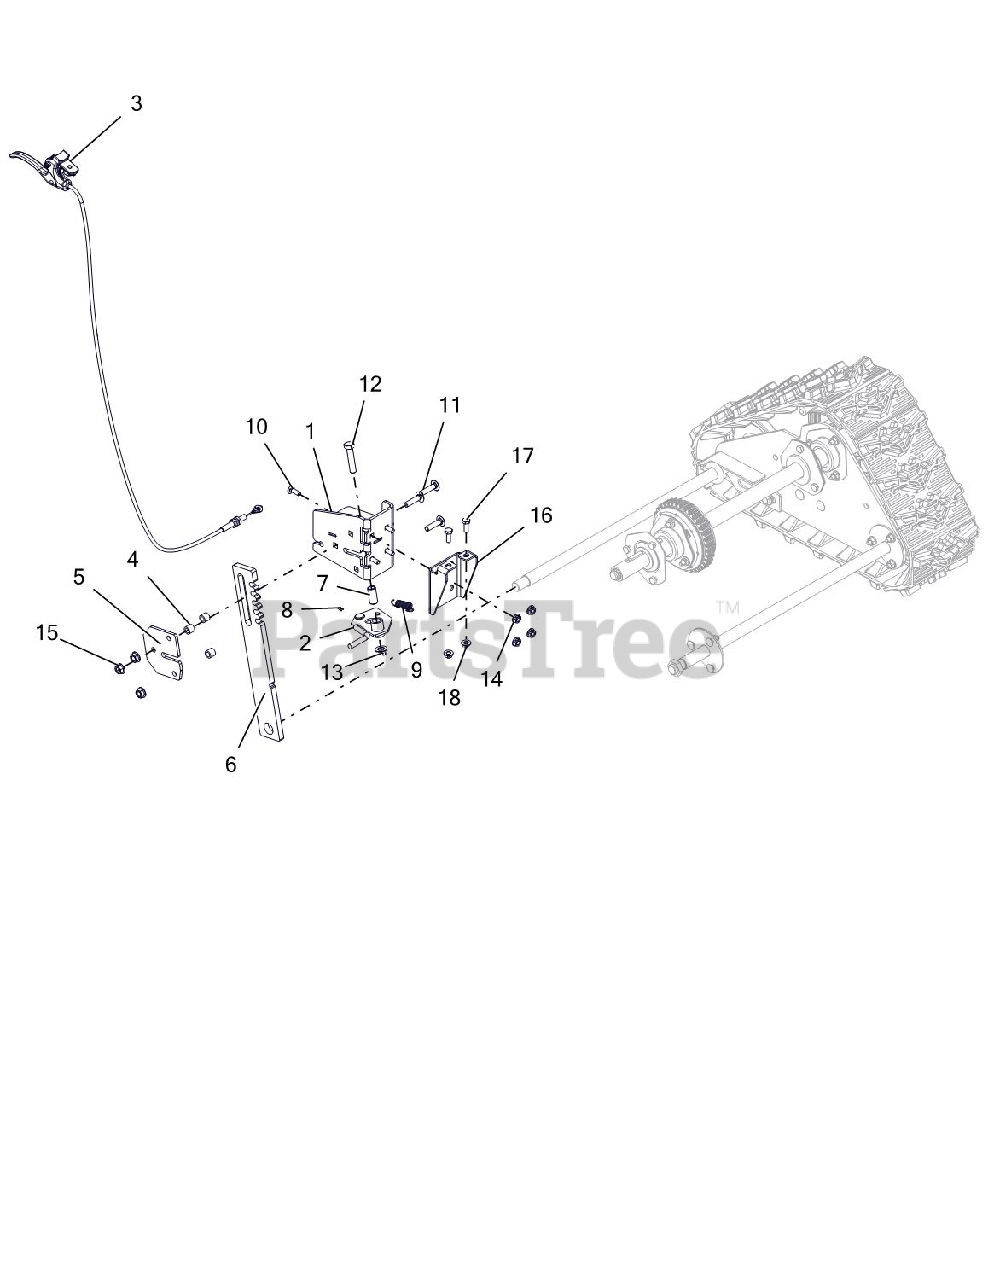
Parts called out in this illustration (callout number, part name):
1	BRACKET,HEIGHT ADJUSTER-DELUXE
2	LOCK,HEIGHT ADJUSTER TRIGGER
3	CABLE, TRACK REMOTE
4	SPACER .50 X .32 X .42
5	PLATE, HEIGHT ADJUSTER
6	STOP,HEIGHT ADJUSTER-DELUXE
7	BSHG-SLV .385X.500X1.045
8	PIN-HAIR INT .06X.18X.77
9	SPRING-EXT .047 X .438 X 1.85
10	@BLT-RDHDSQNK .25-20X.75 G5YZ
11	@BLT-RHDSHSQNK.31-18X1.25 G5YZ
12	@BLT-HEX .38-16X1.75 GR5 YWZC
13	NUT-LK-CTR-FLG .38-16 YWZC
14	@NUT-LK-CTR-FLG .25-20 YWZC
15	@NUT-LK-TOP-FLG .31-18 YWZC
16	BRACKET, REINFORCEMENT
17	@BLT-HEX .25-20X.75 GR5 YWZC
18	@NUT-LK-CTR-FLG .25-20 YWZC
